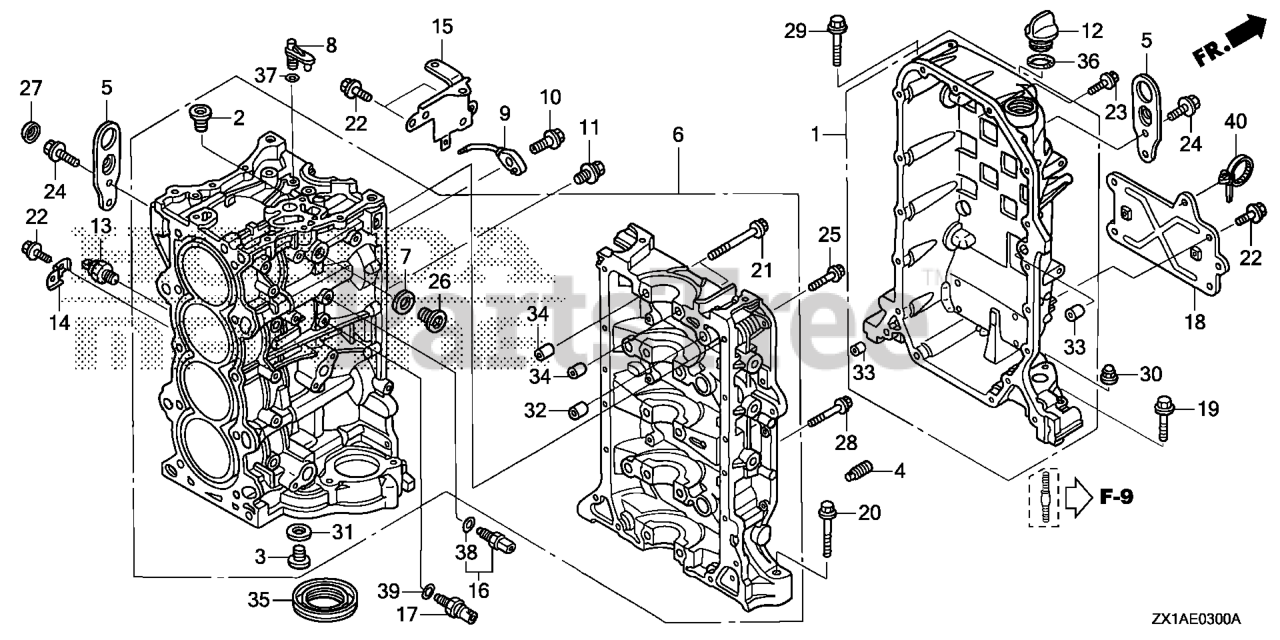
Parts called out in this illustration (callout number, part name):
1	CRANKCASE
2	BOLT, SEALING (20MM)
3	BOLT, SEALING (28MM)
4	ORIFICE, BLOCK (LOWER)
5	HANGER, ENGINE
6	BLOCK ASSY., CYLINDER *NH8* (DARK GRAY)
6	BLOCK ASSY. *NH8*
7	WASHER, SEALING (22MM)
8	ORIFICE, OIL JET
9	BODY, OIL JET
10	BOLT, OIL JET
11	BOLT-WASHER (8X10)
12	CAP, OIL
13	SENSOR ASSY., KNOCK
14	BRACKET, CLIP B
15	BRACKET D, HARNESS CLIP
16	SENSOR ASSY., WATER TEMPERATURE
17	SENSOR, OIL PRESSURE
18	BRACKET, RELAY
19	BOLT, FLANGE (8X55)
20	BOLT, FLANGE (12X83)
21	BOLT-WASHER (11X95)
22	BOLT, FLANGE (6X14) (CT200)
23	BOLT, FLANGE (6X25)
24	BOLT, FLANGE (8X20)
25	BOLT, FLANGE (8X35)
26	BOLT, SEALING (22MM)
27	CAP, BOLT (8MM)
28	BOLT, FLANGE (8X50)
29	BOLT, FLANGE (10X70)
30	NUT (10MM)
30	NUT, FLANGE CAP (10MM)
31	WASHER, SEALING (28MM)
32	PIN, DOWEL (18X22)
33	PIN, DOWEL (13X20)
34	PIN, DOWEL (13X14)
35	OIL SEAL (80X98X10) (ARAI)
36	O-RING (26X2.7)
37	O-RING (6.5X1.5)
38	O-RING (9.5X1.9)
39	O-RING (13X1.5) (ARAI)
40	CLIP, HARNESS BAND (145MM) (BLACK)
